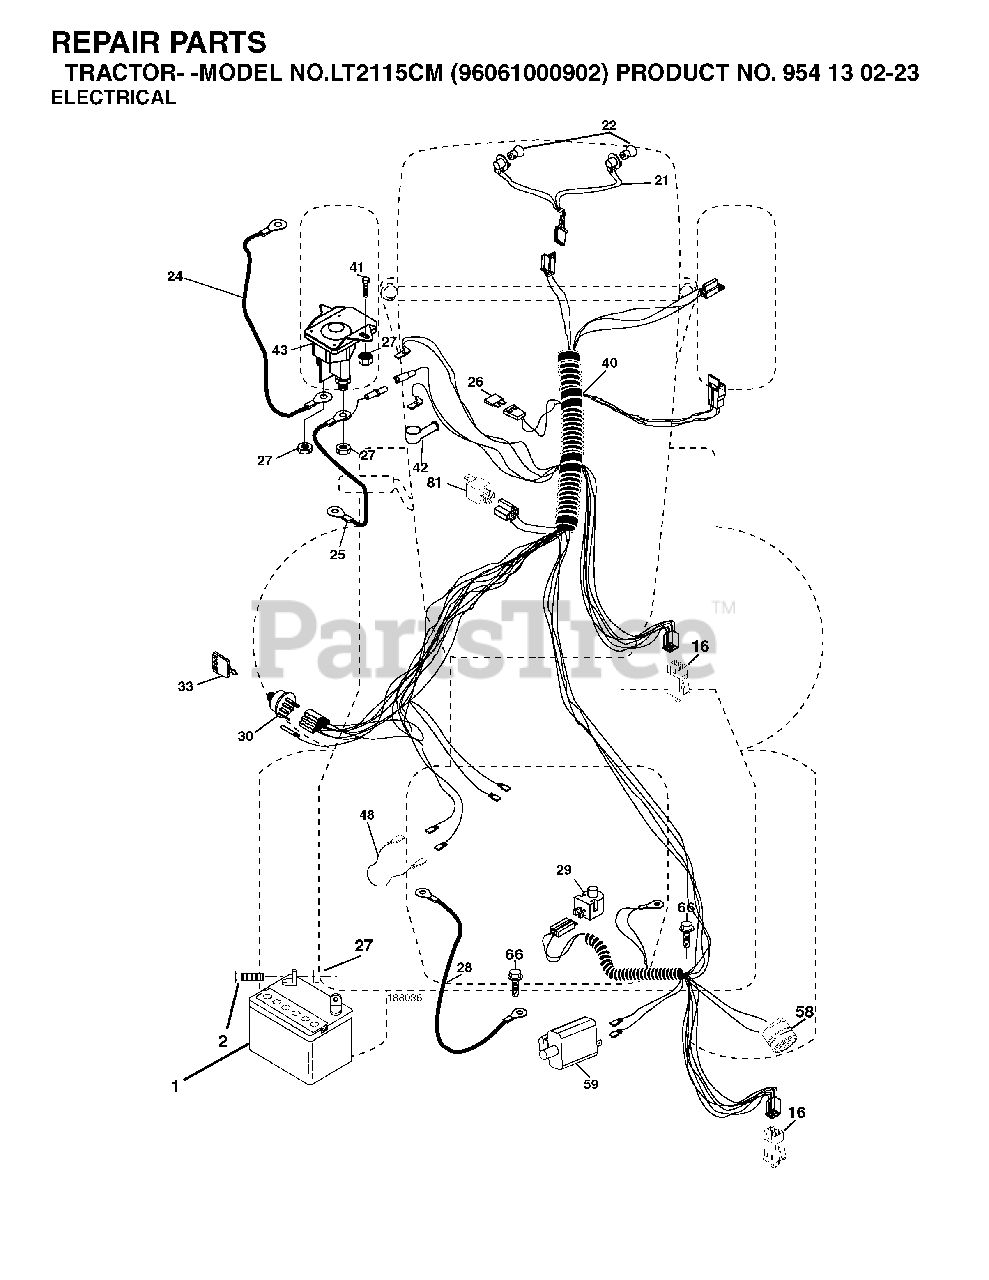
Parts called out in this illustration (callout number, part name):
1	BATTERY 12V .35 AMP
16	SWITCH INTERLOOK PUSH-IN
21	HARNESS ASSY LIGHT
22	LIGHTBULB
24	BATTERY CABLE GT
25	CABLE BATTERY
26	FUSE 20AMP
27	NUT
28	CABLE GROUND
29	SWITCH SEAT
30	IGNITION SWITCH
33	KEY MLD GEN DELTA
42	TERMINAL COVER
43	SOLENOID.W/BRASS.PLUNG
58	BUZZER
81	RELAY.ASSY.T
